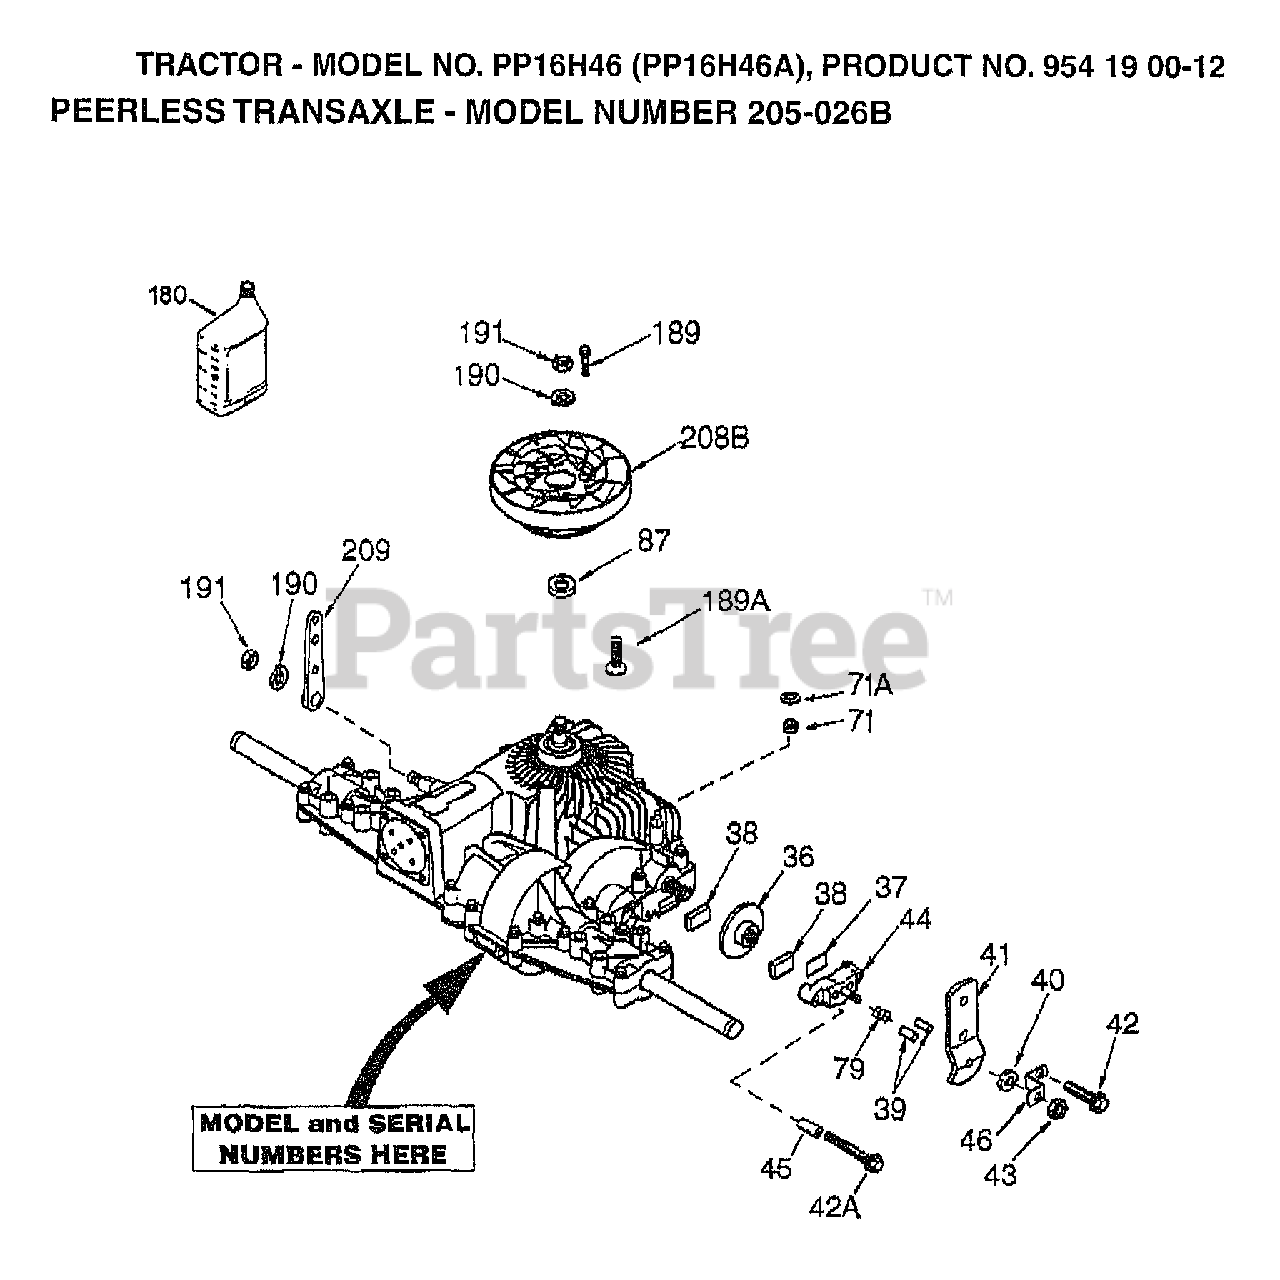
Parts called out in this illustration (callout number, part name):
37	PLATE BRAKE PAD
41	BRAKE LEVER
42	SCREW, 1/4-20 X 1-1/4
42A	SCREW, 1/4-20 X 2-1/4
43	LOCKNUT 5/16-24
44	HOLDER BRAKE PAD
46	BRAKE LEVER BRACKET
71	SEAL SQUARE CUT
180	GEAR OIL 80W90
189	DRIVE SCREW
208B	FAN/COUPLING
209	CONTROL LEVER
